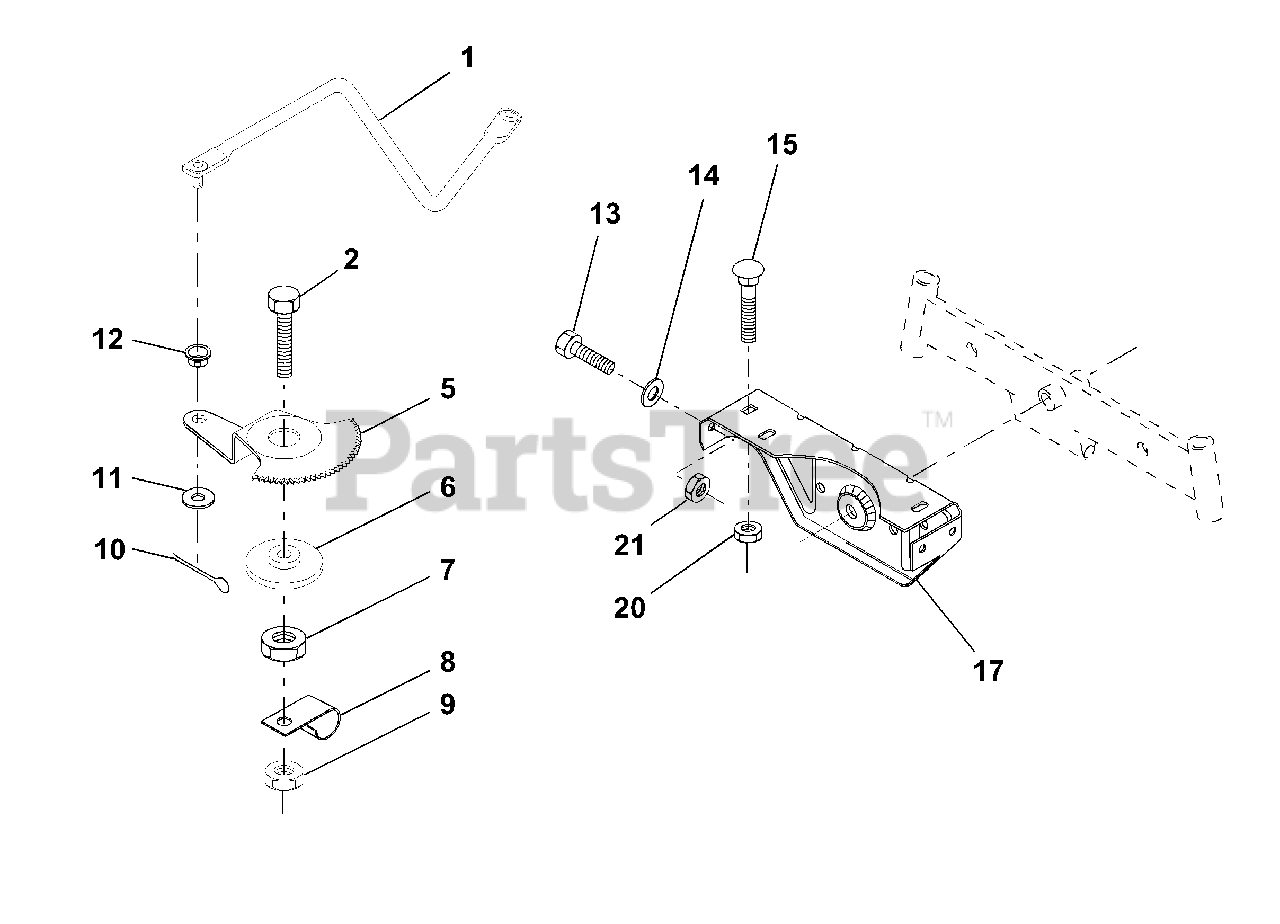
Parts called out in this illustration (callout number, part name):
1	Link, Drag
2	Bolt, Fin Hex 1/2-13 x 1-3/4
5	Gear, Sector
7	Nut, Heavy Hex Top Lock 1/2-13 UNC
8	Clip, Insulated
9	Nut, Crownlock 3/8-16
10	Pin, Cotter 1/8 x 3/4
11	Washer, 13/32 x 13/16 x 16 Ga.
13	Bolt, Hex Hd. 5/16-18 UNC x 3/4
14	Washer 11/32 x 7/8 x 16 Ga.
15	Bolt, Carriage 3/8-16 UNC x 3/4
17	Support, Front Axle
20	Nut, Crownlock 3/8-16 UNC
21	Nut, Crownlock 5/16-18
